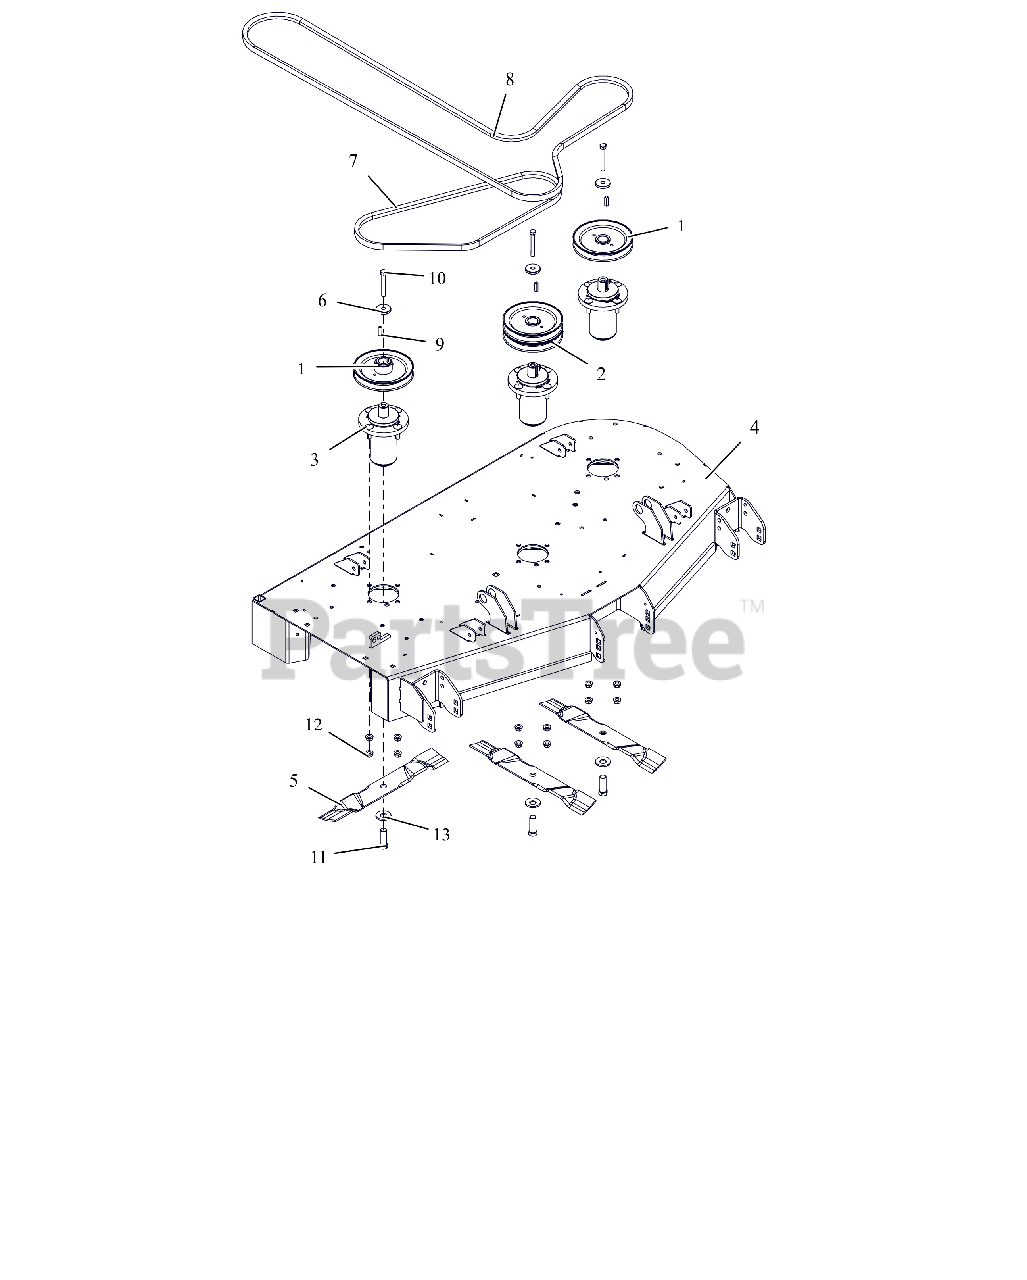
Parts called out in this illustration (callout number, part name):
1	PULLEY, SINGLE-1"ID X 6" OD
2	PULLEY, DOUBLE
3	ASM, MAINT FREE ALUM SPINDLE
4	WLDMT, 48'' CE SIDE DISCH DECK (ORANGE)
5	BLADE, MULCH 16.25
6	RETAINER, SHEAVE
7	V-BELT, B-COGGED
8	V-BELT, HB SECTION
9	KEY, SQ .25X.25X1.00 RC 40-50
10	BLT, HEX .38-16X2.75 G8 ZCC
11	BLT, HEX .62-18X1.75 G8 ZCC
12	NUT-LK-CTR-FLG .375-16 GF ZCC
13	WSHR-BLVL .669X1.535X.138
